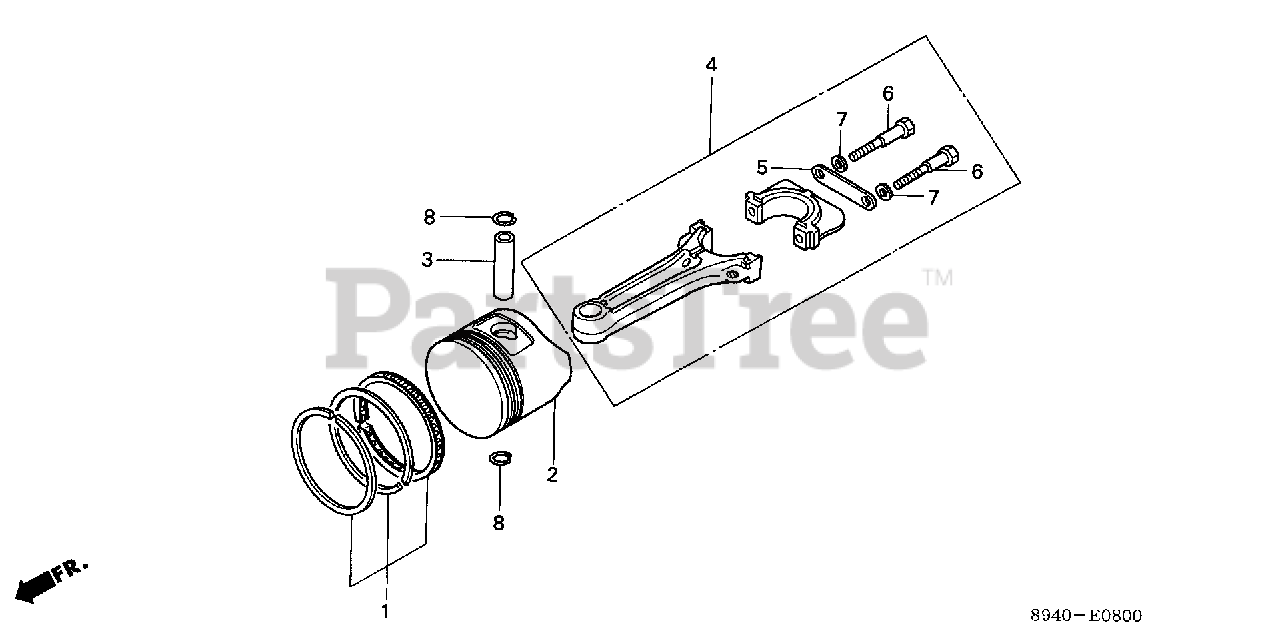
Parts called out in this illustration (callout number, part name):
1	RING SET, PISTON (STD)
1	RING SET, PISTON (OS 0.25)
1	RING SET, PISTON (OS 0.50)
1	RING SET, PISTON (0.75)
2	PISTON (STD)
2	PISTON (OS 0.25)
2	PISTON (OS 0.50)
2	PISTON (0.75)
3	PIN, PISTON
4	ROD ASSY., CONNECTING
5	WASHER A, CONNECTING ROD
5	WASHER, CONNECTING ROD
6	BOLT, CONNECTING ROD (6MM) (NOT AVAILABLE)
6	BOLT, CONNECTING ROD (7MM)
7	WASHER, LOCK (6MM) (N/A: SEE ASSEMBLY)
7	WASHER, LOCK (7MM)
8	CLIP, PISTON PIN (15MM)
